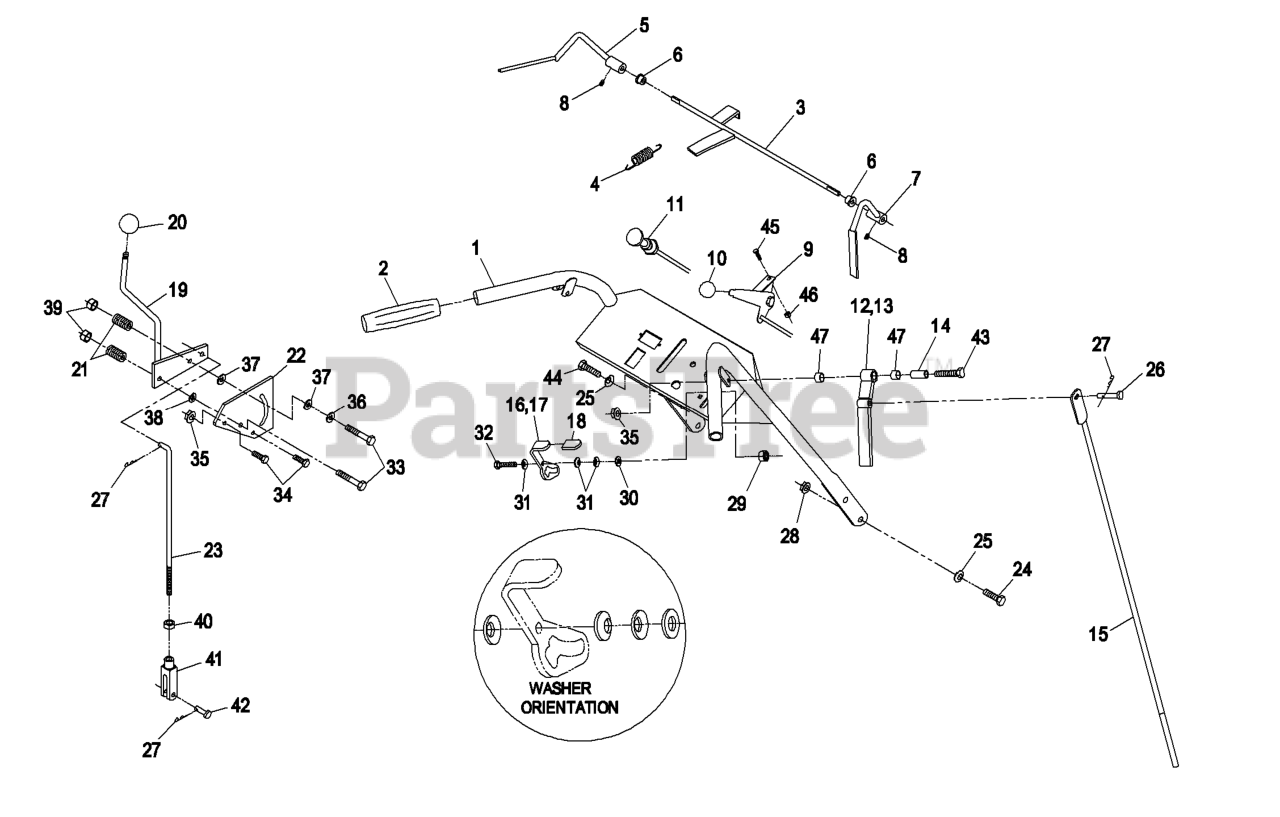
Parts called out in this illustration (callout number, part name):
3	WLD,ROD OPC
4	SPRING-EXTENSION
5	LEVER-LH
6	BUSHING-NYLON
7	LEVER-RH
8	SCREW-SET
9	THROTTLE CABLE ASM
10	KNOB-BALL
11	CONTROL-CHOKE
14	BUSHING-LEVER, DRIVE
15	ROD,DRIVE LEVER
18	GRIP-LATCH
20	KNOB-BALL
21	SPRING-COMPRESSION
22	PLATE-LEVER, SHIFTER
23	ROD,SPEED CONTROL
26	PIN-CLEVIS
27	PIN-COTTER
31	WASHER-SPRING
36	WASHER-FRICTION
37	WASHER-FRICTION
41	YOKE-ADJUSTABLE
42	PIN-CLEVIS
45	BOLT-CARR
47	BUSHING-SLEEVE
